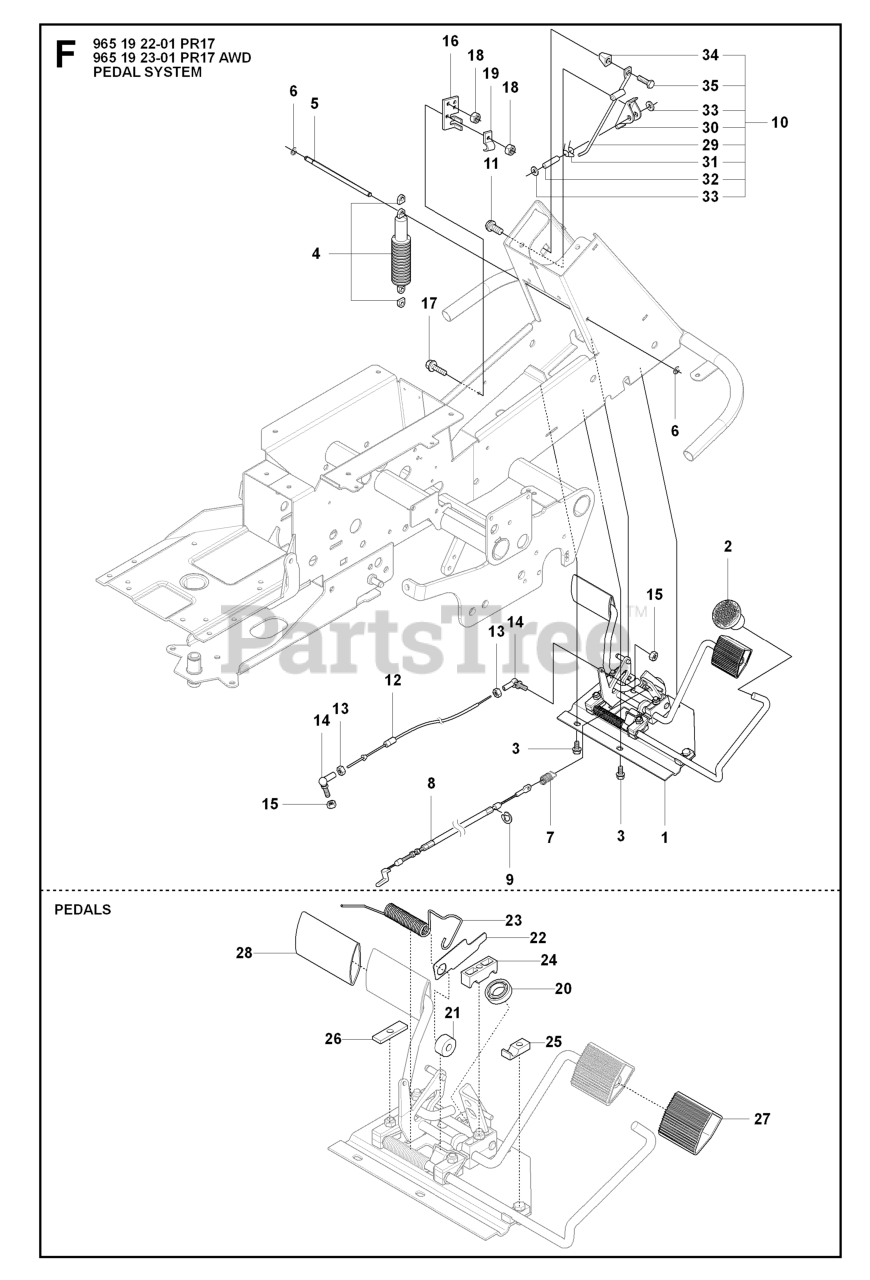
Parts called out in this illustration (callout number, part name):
1	PEDAL ASSEMBLY
2	KNOB
4	SHOCK ABSORBER
8	RP WIRE
8	BRAKE WIRE
14	CONNECTOR
15	LOCKNUT M5
18	LOCKNUT M5
20	BALL BEARING 6002-2RS1
21	ROLLER
22	PLATE
23	SPRING
24	PEDAL SHAFT CLAMP
25	SUPPORT
26	PLATE
27	PEDAL RUBBER
28	PEDAL RUBBER, SF
